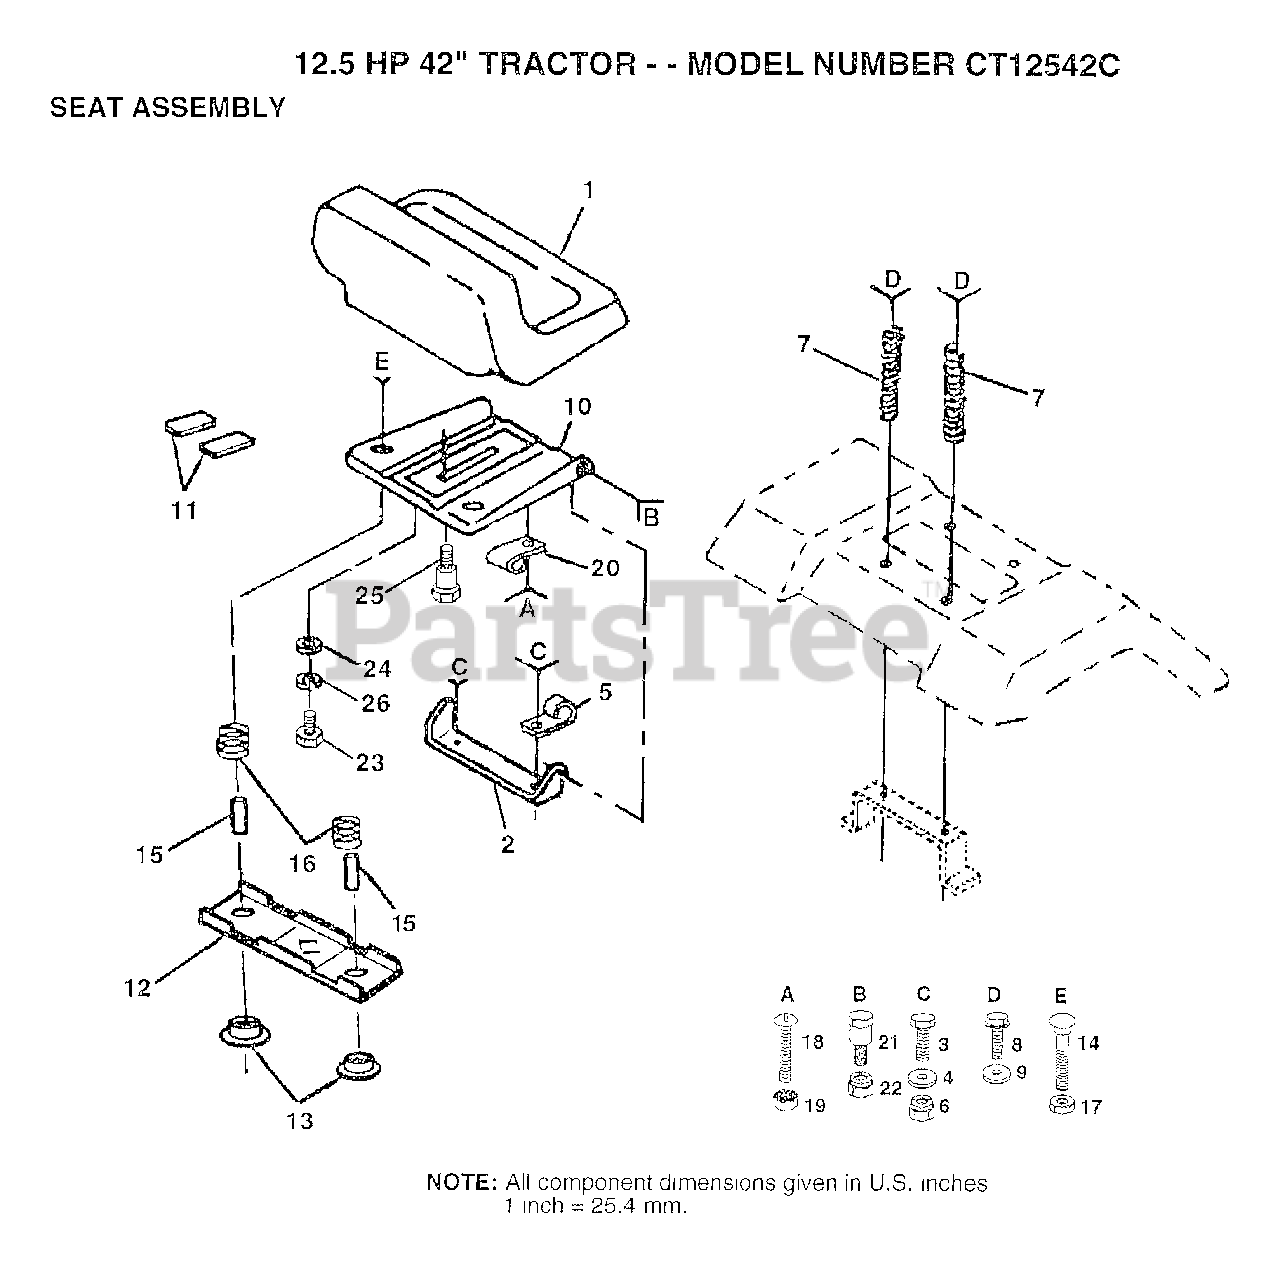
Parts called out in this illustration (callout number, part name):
4	WASHER
5	CLIP T
7	SPRING COMPRESSIO
8	SCREW GTV
9	WASHER
11	STRIP FORM
12	BRKT SWITCH
13	BUSHING
15	SPLIT SPACER
16	SPRING
19	"NUT,KEPS"
23	BOLT
24	WASHER
25	"BOLT,SHOULDER"
26	LOCKWASHER
